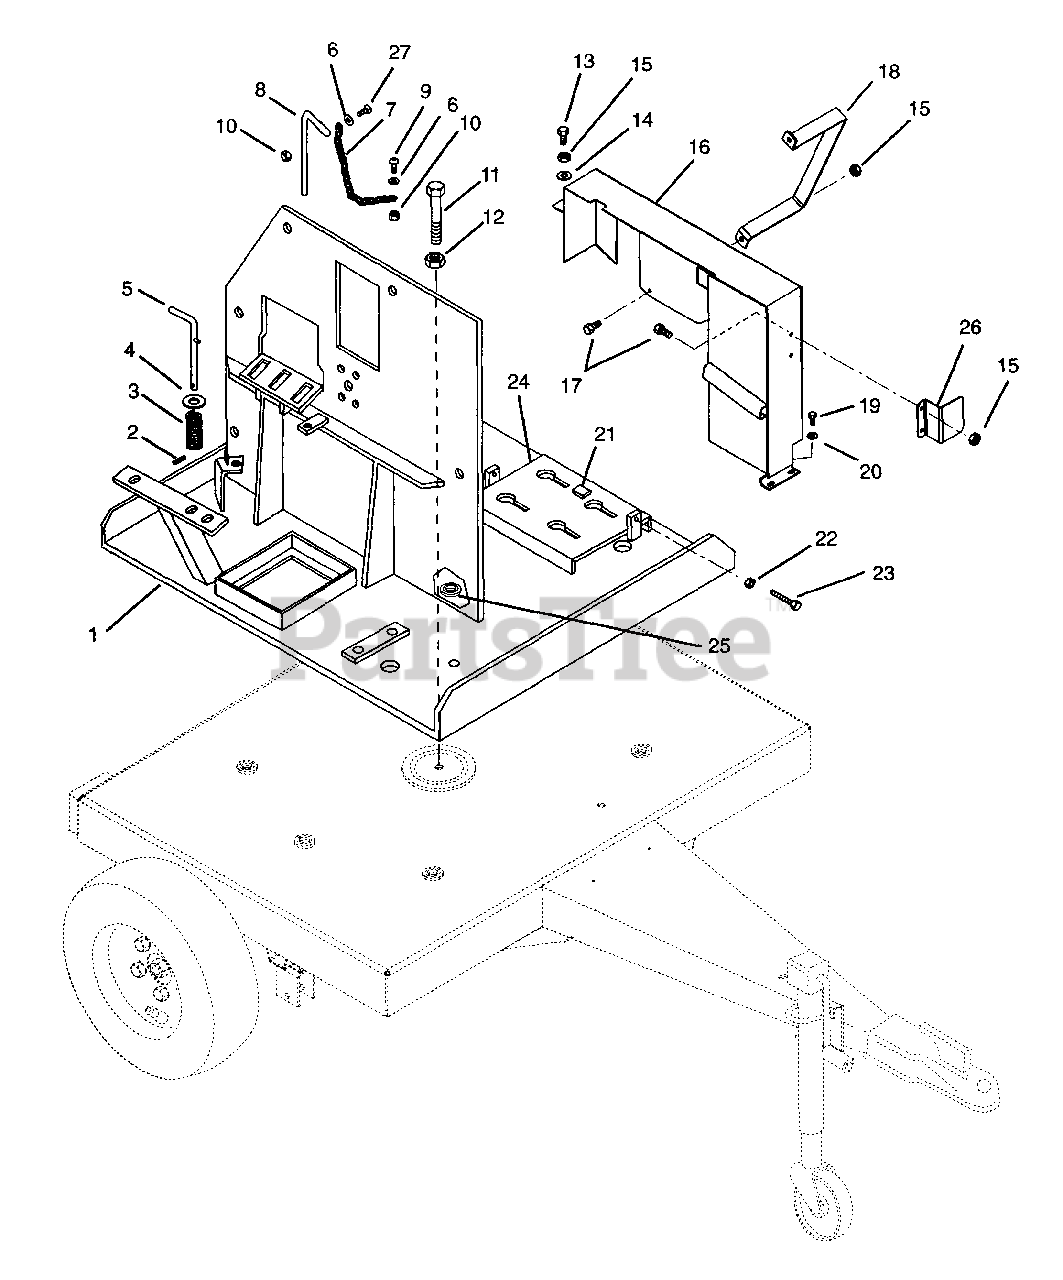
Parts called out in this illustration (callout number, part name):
1	Rotating Base Plate
2	Pin-Roll .188 x 1.50
3	Spring, Compression .080 x .91 x 3.38
4	Washer-Flat-Steel .656 x 1.312 x .095
5	Pin Index
6	Washer-Flat-Steel .219 x .50 x .049
7	Chain-14 Straight Link 44
8	Lock Handle
9	Screw-Machine 10-24 x 1.00 HWH
10	Nut-Locking-Nylon 10-24 w/Insert
11	Bolt-Hex .75-16 x 2.50-Grade 5
12	Nut-Locking-Center .75-10
13	Bolt-Hex .31 x .875 x .083
14	Washer-Flat-Steel .38 x .875 x .083
15	Nut-Locking-Center .31-18
16	Guard Weldment
17	Bolt-Hex .31-18 x .50-Grade 5
18	Guard-Muffler
19	Bolt-Hex .38-16 x 1.00
20	Washer-Lock .375 x .155
22	Nut-Hex .38-18
23	Bolt-Hex .38-16 x 3.50
24	Engine Adjuster
25	Grommet .125 x 1.00 ID
26	Guard-Manifold
27	Screw-Machine 10-24 x 1.00
